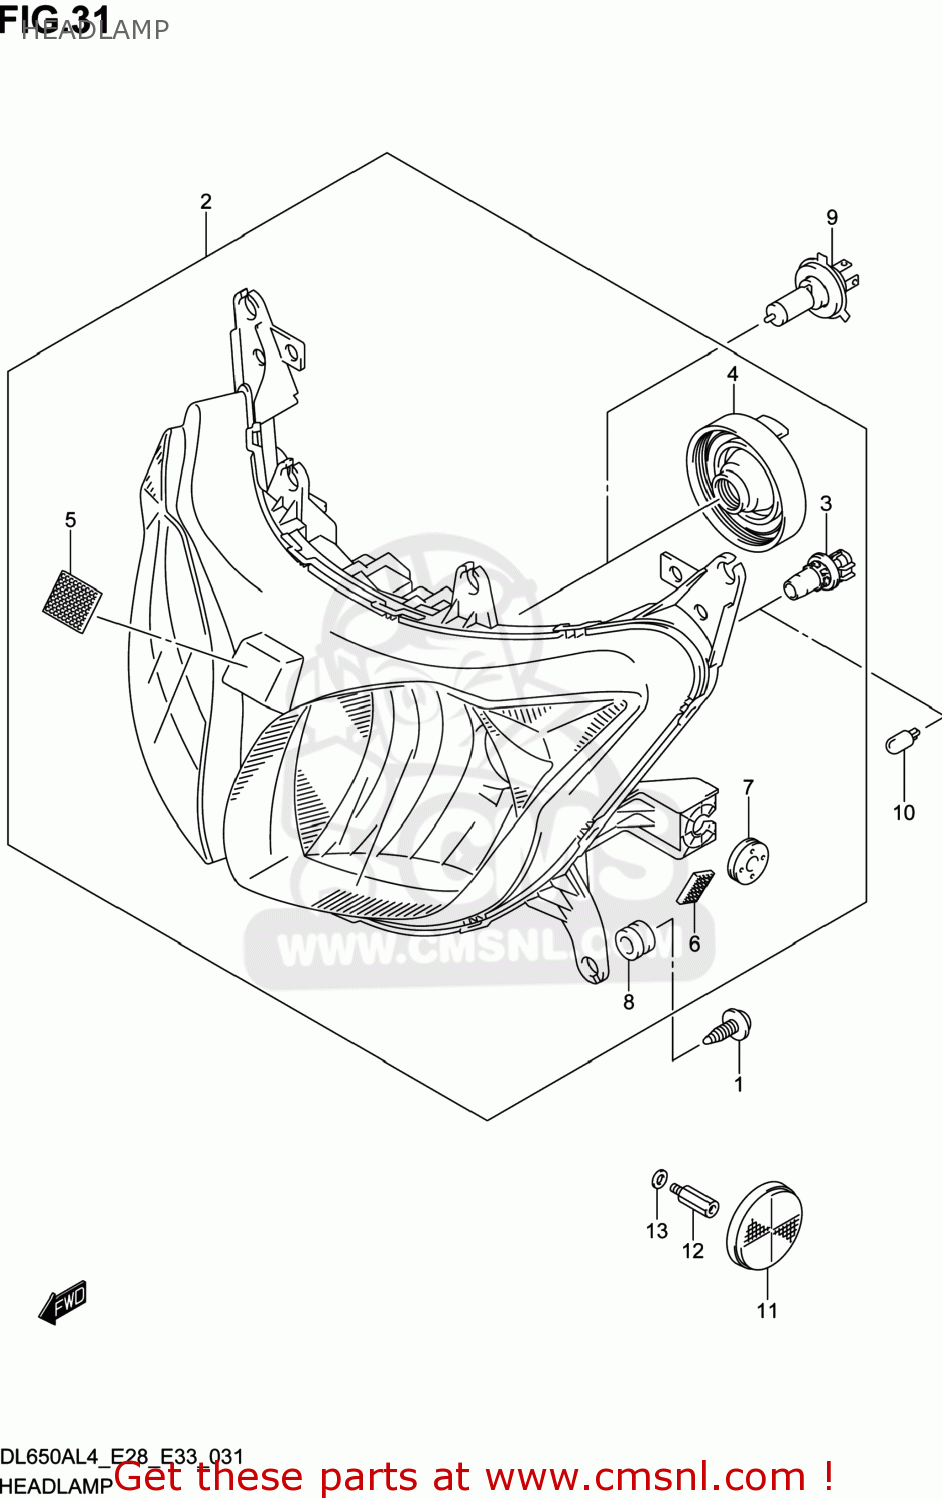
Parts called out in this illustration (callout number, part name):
1	SCREW(5X15)
2	HEADLAMP ASSY
3	SOCKET,POSITION LAMP
4	COVER,SOCKET
5	FASTENER
6	FASTENER,COWLING
7	CUSHION
8	CUSHION
9	BULB(12V60/55W,H4)
10	BULB(12V5W)
11	REFLEX REFLECTOR ASSY,FR SIDE
12	BOLT(5X10)
13	WASHER
